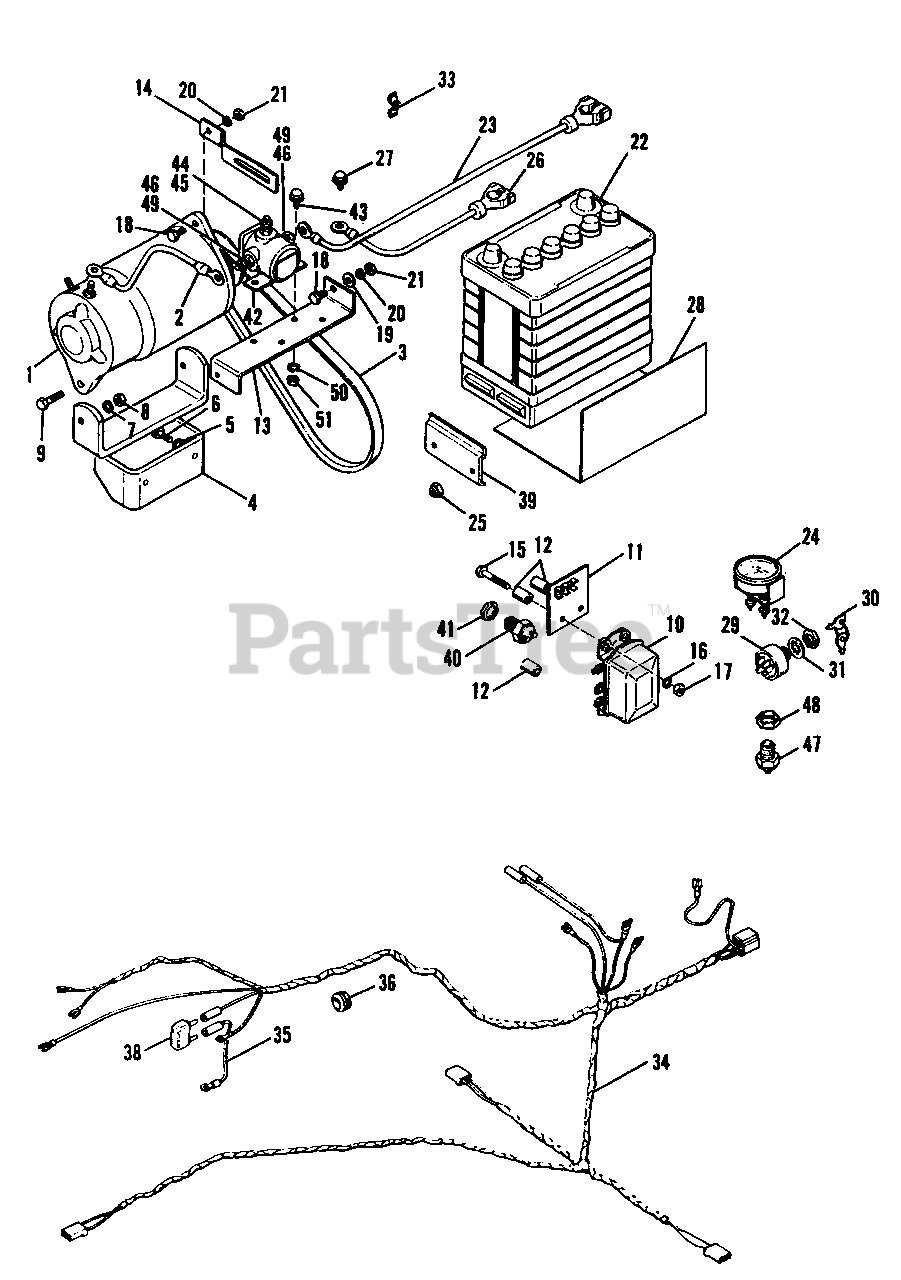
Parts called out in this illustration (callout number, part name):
1	MOTOR, Generator
2	CABLE, Generator to Solenoid
3	V-BELT, 39.12"
4	SUPPORT ASSEMBLY
5	LOCKWASHER, 5/16"
6	CAPSCREW, Hex, 5/16-18 x 3/4" lg.
7	LOCK WASHER, 5/16"
8	NUT, Hex, Full, 5/16"-18
9	CAPSCREW, Hex, 5/16"-18 x 1-1/4"
10	REGULATOR, Voltage
11	BOARD, Terminal
14	ARM, Adjusting, Generator
15	CAPSCREW, Hex, 1/4"-20 x 1-3/4" lg.
16	LOCKWASHER, Shakeproof, 1/4"
17	NUT, Hex, Full, 1/4"-20
18	CAPSCREW, Hex, 5/16"-18 x 3/4" lg.
19	WASHER, Plain 5/16"
20	LOCKWASHER, 5/16"
21	NUT, Hex, Full, 5/16"-18
23	CABLE, Battery
25	NUT, Elastic, Stop, 5/16"-18
26	CABLE, Battery to Ground
27	SCREW, Hex, Washer Hd. 1/4"-20 x 1/2" lg.
28	INSULATION, Fuel Tank
29	SWITCH, Ignition
30	KEY & RING ASSEMBLY
31	LOCK WASHER, Int. 5/8"
32	NUT, Hex, Special
33	CLIP, Wire
34	HARNESS ASSEMBLY
35	WIRE ASSEMBLY
38	BREAKER, Circuit
39	CLAMP, Battery
40	SWITCH, Safety
41	NUT, Pal, 9/16"-18
43	SCREW, Hex, Washer Hd., 1/4"-20 x 1/2" lg.
44	NUT I Hex, Full, #10-32
45	LOCKWASHER, Shakeproof, #10-32
46	NUT, Hex, Full, 5/16"-1
47	SWITCH, Safety
48	NUT, Pal
49	LOCKWASHER, 5/16"
50	LOCKWASHER, 1/4"
51	NUT, Hex, Full, 1/4"-20
